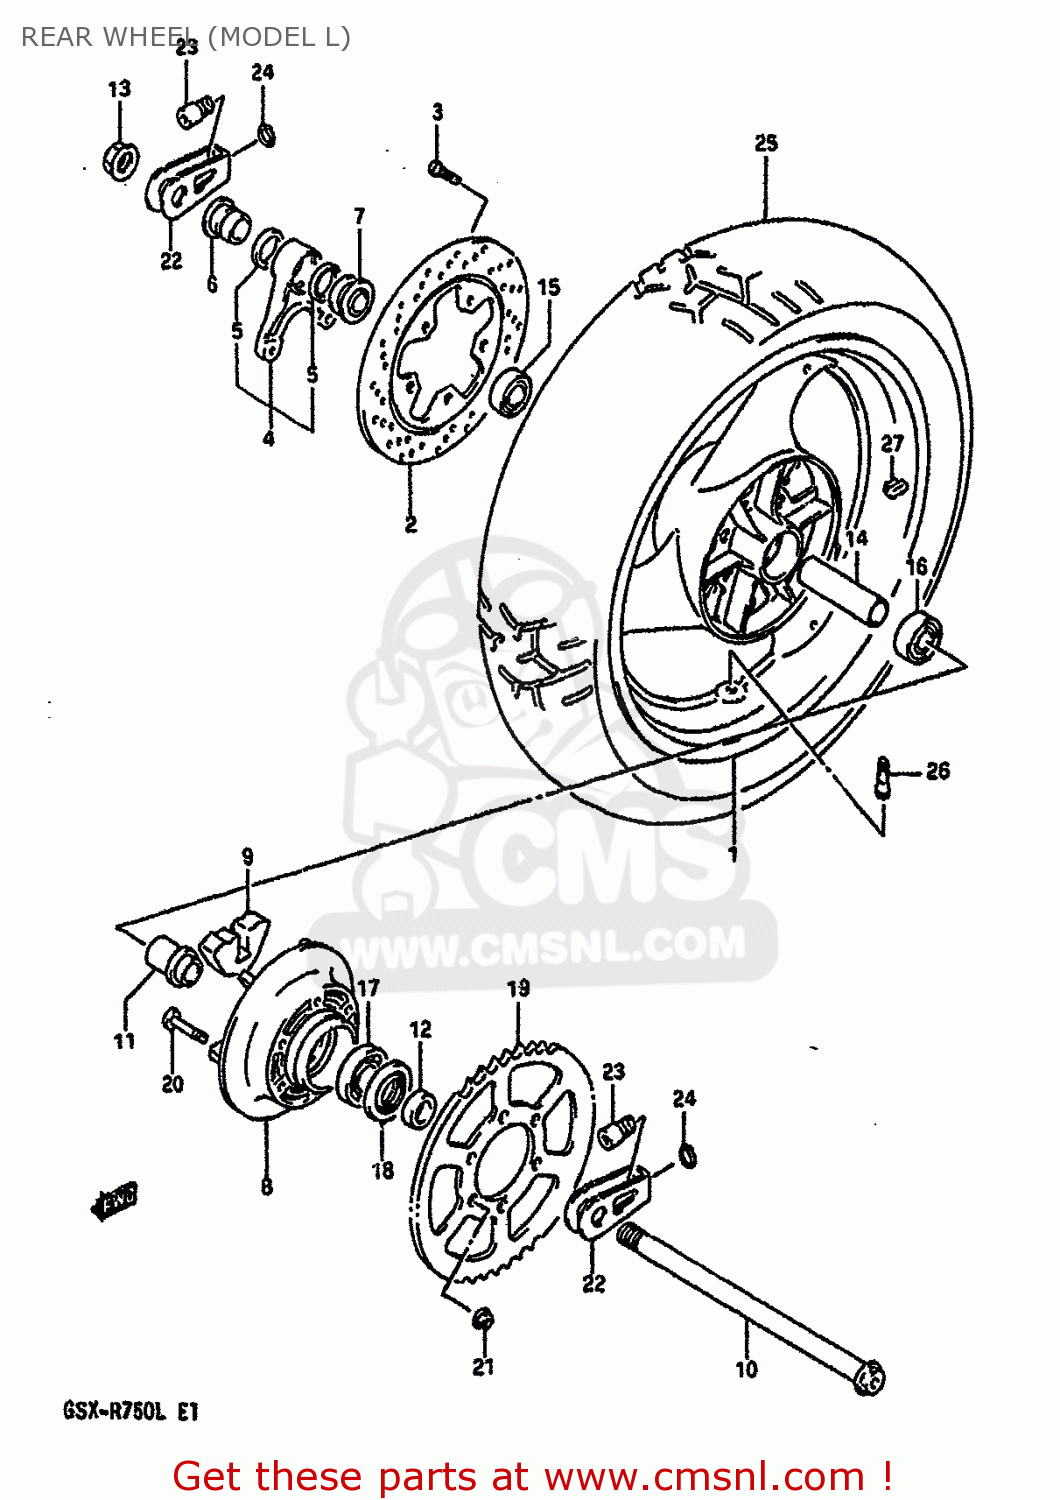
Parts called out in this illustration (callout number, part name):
1	WHEEL,RR(17XMT5.50)
2	DISC,RR BRAKE
3	BOLT
4	BRACKET,RR CALIPER
5	SEAL,OIL(28X35X5)
6	SPACER,RR CALIPER BRACKET
7	SPACER,RR AXLE,R
8	DRUM,RR SPROCKET
9	ABSORBER,RR HUB SHOCK
10	AXLE,RR
11	RETAINER,RR HUB BEARING
12	SPACER,RR AXLE,L
13	NUT
14	SPACER,RR WHEEL HUB BEARING
15	BEARING(20X47X14)
16	BEARING(20X47X14)
17	BEARING(25X62X17)
18	SEAL,OIL(35X62X8)
19	SPROCKET,REAR
20	BOLT
21	NUT
22	ADJUSTER,CHAIN
23	ADJUSTER,CHAIN
24	CIRCLIP
25	TIRE
26	VALVE ASSY,WHEEL RIM(TR412)
27	BALANCER,WHEEL
28	BALANCER,WHEEL
29	CAP,CHAIN ADJUSTER
